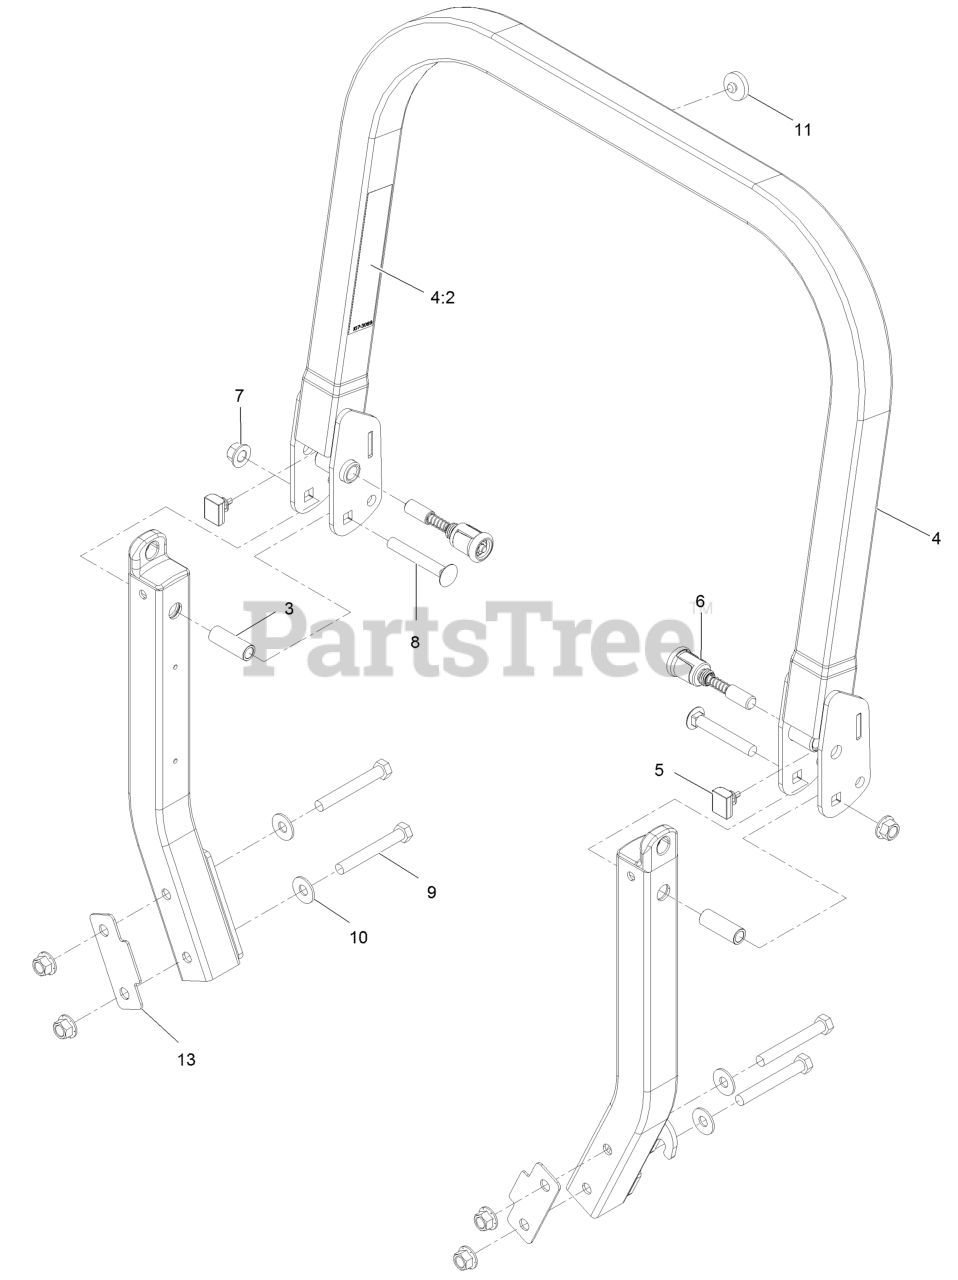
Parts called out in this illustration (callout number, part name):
4	UPPER ROPS ASM
4:2	DECAL-WARNING
5	BUMPER-ROPS
6	PIN-SPRING
7	Nut-Lock 1/2-13
8	SCREW-CARR
9	SCREW-HH
10	WASHER-SPRING
11	BUMPER-PUSH-IN, RUBBER
